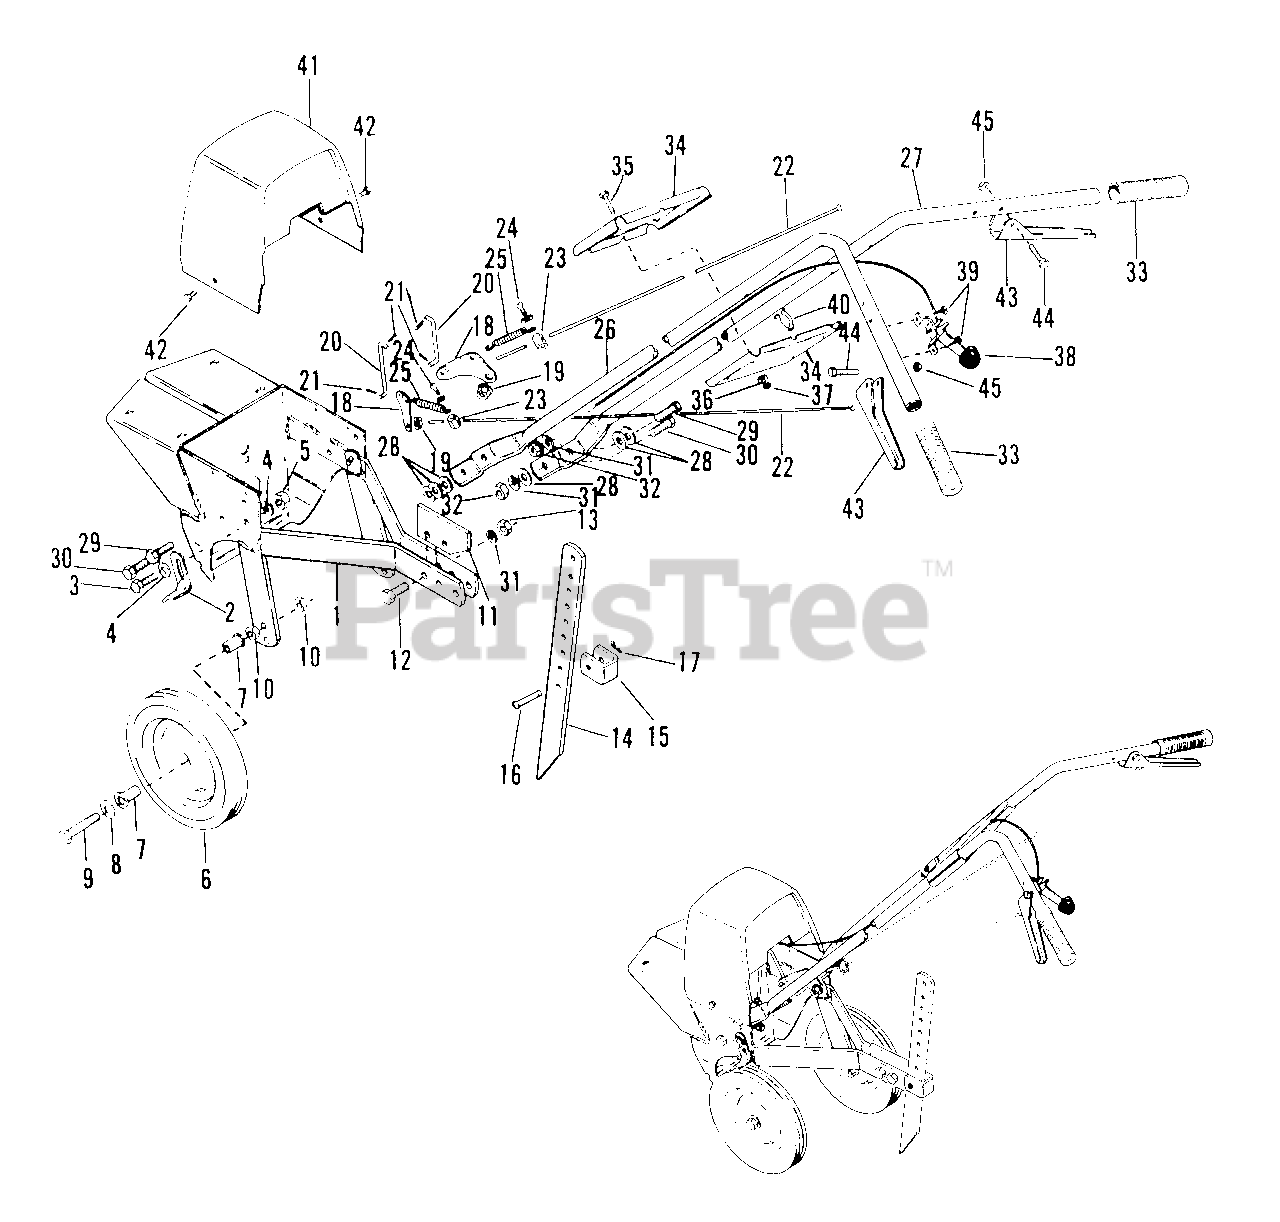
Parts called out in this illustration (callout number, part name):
1	FRAME ASSY
2	SCRAPER
3	CAPSCREW, Hex, 3/8-16 x 3/4
4	LOCKWASHER, 3/8
5	NUT, Hex, 3/8-16
6	WHEEL & TIRE ASSY
7	BUSHING, Wheel
8	WASHER, Flat, 1/2
9	CAPSCREW, Hex, 1/2-13 x 3-1/4
10	NUT, Hex, 1/2-13
11	PLATE, Stop
12	CAPSCREW, Hex, 3/8-16 x 1
13	NUT, Hex, 3/8-16
14	BAR, Depth
17	CLIP, Hair Pin
18	BELLCRANK
19	LOCKNUT, Flange
20	LINK, Rod
21	PIN, Cotter, 1/16 x 3/4
22	ROD, Control
23	CLAMP, Wire
24	SETSCREW, #10-24 x 5/8
26	HANDLE, L.H.
27	HANDLE, R.H.
28	WASHER, Flat, 3/8
29	SCREW, Hex, Whiz-Lock, 3/8-16 x 1
30	CAPSCREW, Hex, 3/8-16 x 1-1/4
31	LOCKWASHER, 3/8
32	NUT, Hex, 3/8-16
34	COVER, Upper Handle
36	LOCKWASHER, 1/4
37	NUT, Hex, 1/4-20
38	CONTROL ASSY, Throttle
39	SCREW, #10-24 x 1/2
40	CLIP, Cable
42	SCREW, Self-Tapping, 1/4-20 x 3/8
43	GRIP, Clutch
45	LOCKNUT, Hex, 1/4-20
